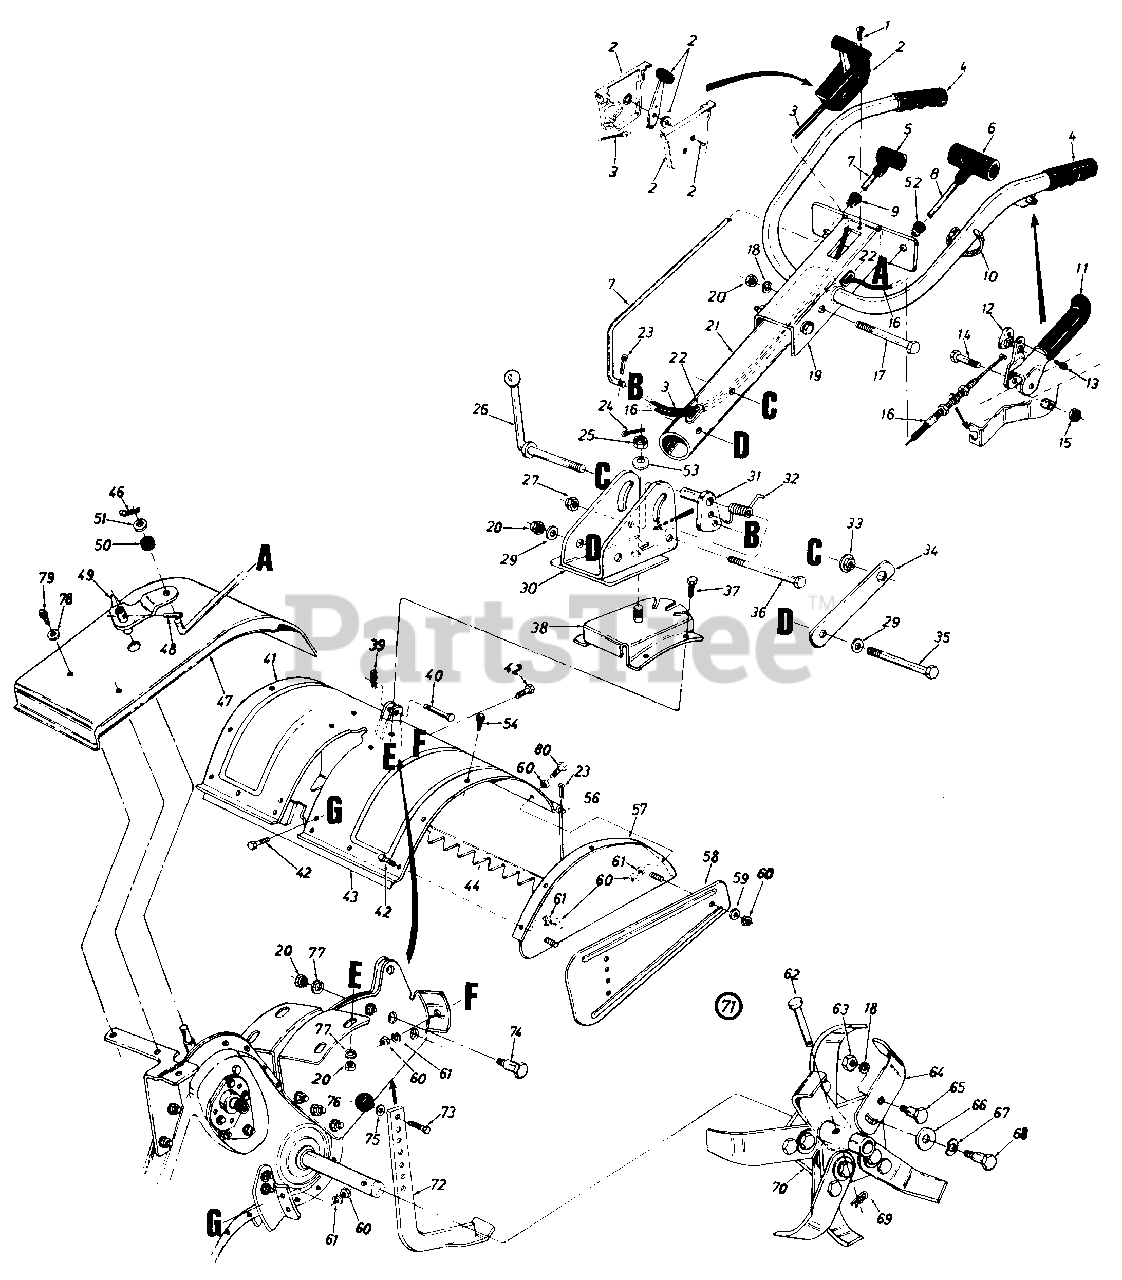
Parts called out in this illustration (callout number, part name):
1	Truss Mach. AB-Tap. Scr. #10 x .50" Lg.
2	Throttle Control Box Ass'y.
3	Throttle Control Wire
4	Handle Grip
5	Small "T" Knob
6	Large"T" Knob
7	Clutch Rod
8	Control Rod 37" Lg.
9	Snap On Bushing 3/8" Dia.
10	Cable Tie-Self Clinching
12	Barrel Cable Hold Down
13	Hex B-Tap Scr. #10 x .44" Lg.
14	Hex Bolt 3/8-16 x 2.0" Lg.
15	Hex Cent. L-Nut 3/8-16 Thd.
16	Clutch Control Cable 53" Lg.
17	Hex Bolt 3/8-16 x 3.00" Lg.
18	L-Wash. 3/8" I.D. H.D.
19	Handle Ass'y.
20	Hex Nut 3/8-16 Thd.
23	Cotter Pin 3/32" Dia. x .75" Lg.
24	Cotter Pin 3/32" Dia. x 1.25" Lg.
25	Hex Slotted Nut 5/8-18 Thd.
26	Handle Adj. Crank
27	Hex Cent. L-Nut 3/8-16 Thd.
29	Bell-Wash. .4" I.D. x .87" O.D.
30	Handle Pivot Bracket
31	Positioner Crank Ass'y.
32	Spring Handle Adj.
33	Hex Flange Nut 3/8-24 Thd.
34	Bracket Hex Nut Retainer
35	Hex Bolt 3/8-16 x 3.25" Lg.
36	Hex Bolt 3/8-16 x 3.00" Lg. 0 0 Grade 8
37	Hex Bolt 3/8-16 x .75" Lg.
40	Clevis Pin 375" Dia.
43	Bracket Reinforcement 18"
46	Intern. Cotter Pin 5/16" Dia.
49	Shifting Crank Ass'y.
50	Rubber Washer .33" I.D.
51	Fl-Wash. .4" I.D. x 1.25" O.D.
52	Snap On Bushing 1/2" Dia.
53	Bell-Wash. .63" I.D. x 1.25"
54	Hex Wash. Tap Scr.
56	Tiller Flap Rod
60	Hex Nut 5/16-18 Thd.
61	L-Wash. 5/16" I.D.
62	Clevis Pin .375" Dia.
63	Hex Nut 3/8-24 Thd.
65	Shld. Bolt 1/2" Dia. x .175
66	Fl-Wash. .51" I.D. x 1.50"
67	Bell-Wash. .515" I.D. x 1.14"
68	Shld. Bolt 1/2" Dia. x .320
69	Intern. Cotter Pin
73	Hex Bolt 3/8-16 x .75" Lg.
74	Shld. Bolt 1/2" I.D. x .62" Lg.
75	Fl-Wash. 3/8" I.D. x 5/8" O.D.
76	Ball Knob
77	L-Wash. 3/8" I.D.
78	Fl-Wash. .281" I.D. x .62"
79	Hex Wash. Self-Tap Scr. 1/4-20 x .50" Lg.
80	Hex Bolt 5/16-18 x 1-1/4" Lg.
